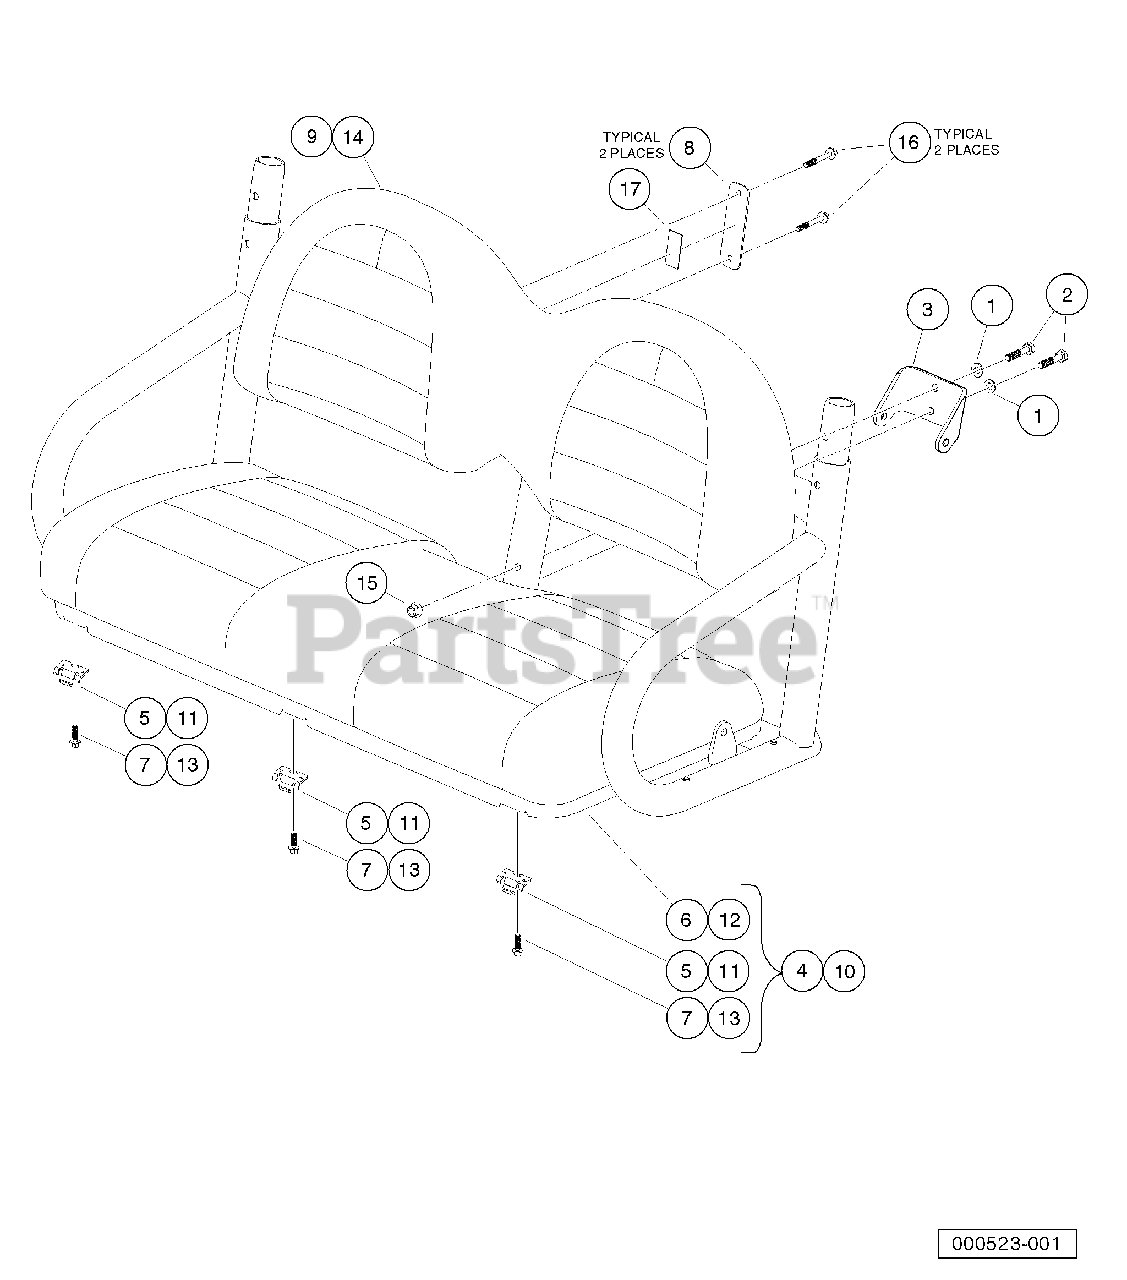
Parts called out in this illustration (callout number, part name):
1	Washer, Hard, M10, Zn-Ni/Blk
2	Bolt, M10 X 45, Zn-Ni
3	Bracket, Seat Belt, Bench
4	Asm, Seat Bottom, Bench, Gray
5	Hinge Plate
6	Asm, Seat Bottom, Bench
7	Bolt Flg Blk, M8 X 25, Loctite
8	Bracket, Seat Back, AWD
9	Seat Back, Bench, Gray
10	Asm, Seat Bottom, Bench, Black
11	Hinge Plate
12	Seat Bottom, Bench, Black
13	Bolt Flg Blk, M8 X 25, Loctite
14	Seat Back, Bench, Black
15	Nut, Flanged, M10 x 1.5, Black
16	Bolt Flg Blk, M8 X 55, Loctite
17	Tape, Double-Sided, VHB, 1"x 2"
